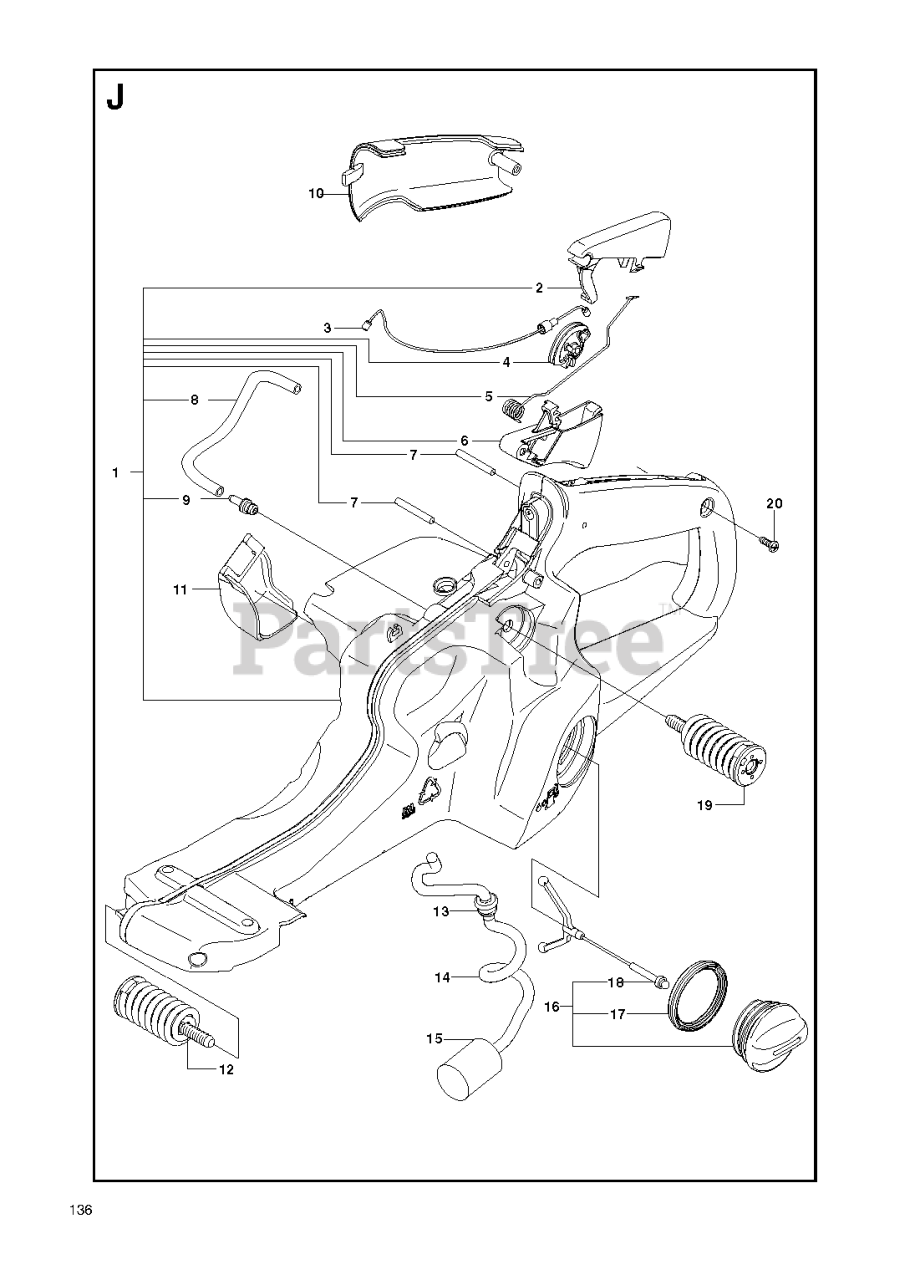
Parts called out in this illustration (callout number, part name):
2	THROTTLE LOCKOUT
3	THROTTLE WIRE
6	THROTTLE TRIGGER
7	PIN 3X25
8	HOSE
9	FUEL TANK VENT
10	COVER GZ7000
12	VIBRATION ABSORBER
13	FUEL TANK BUSHING
14	FUEL HOSE
15	FUEL FILTER
16	TANK CAP
17	SEALING
18	TANK LOCK
19	VIBRATION ABSORBER
